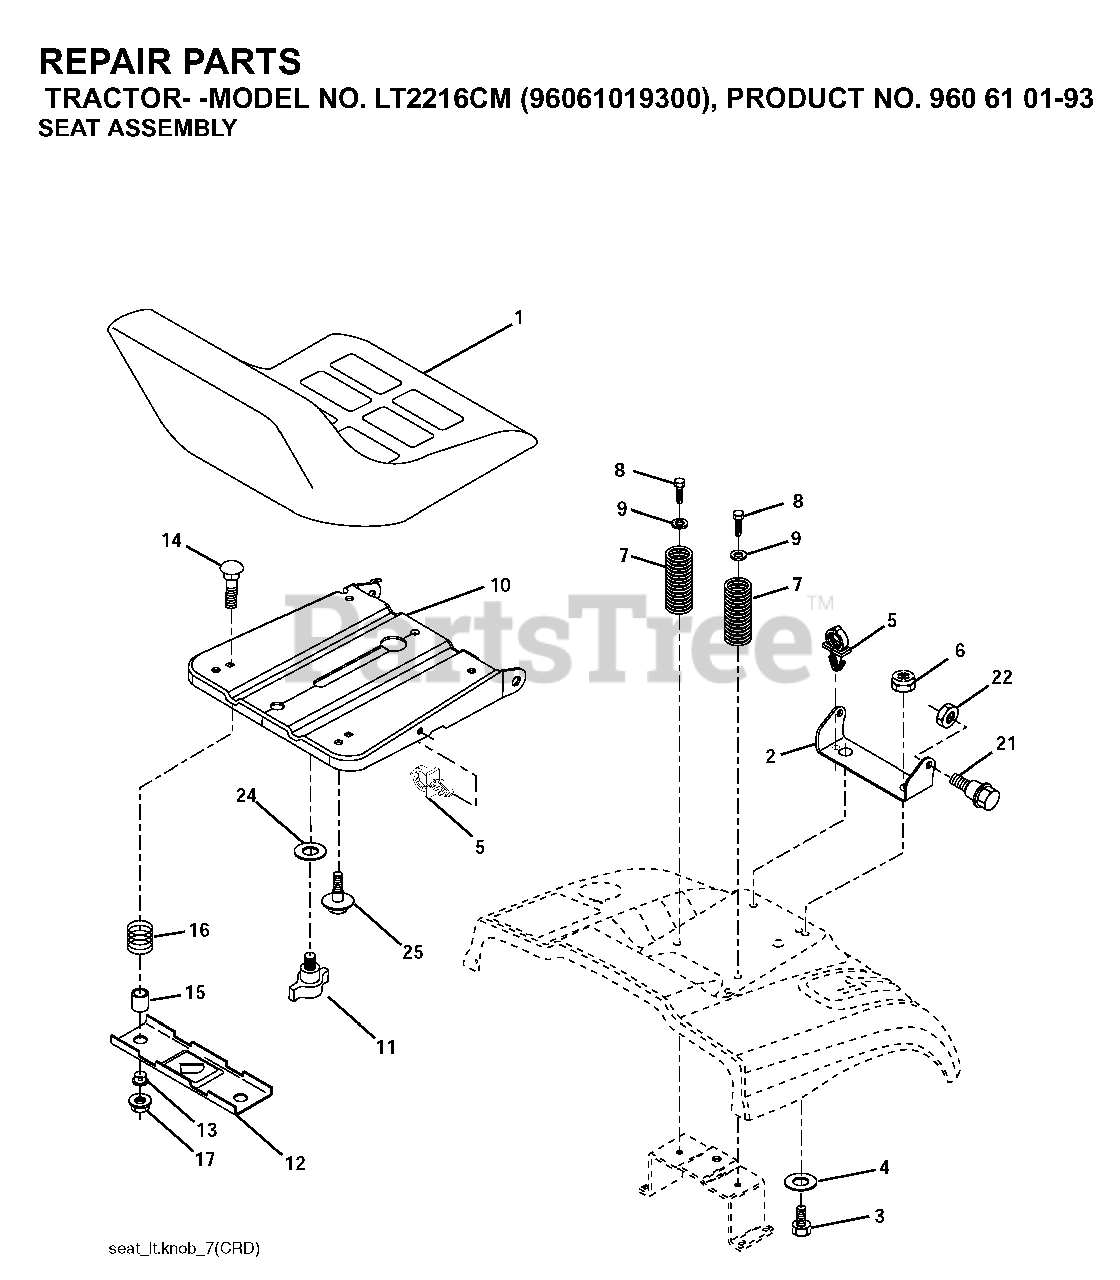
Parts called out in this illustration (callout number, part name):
2	SEAT PIVOT BRKT
4	WASHER PM
5	PUSH CLIP
6	NUT
7	SPRING COMPRESSION
8	SCREW 3/8-16X1
9	WASHER
10	PAN.ASM.SEAT.1SLOT
11	KNOB.SEAT.ADJ.WINGNUT
12	BRKT.MNTNG.SWITCH.SEAT
14	BOLT.ROUND.HEAD.SQUARE.NECK
15	SPACER SPLIT 28X.96
17	NUT T
21	BOLT.SHOULDER.5/16-18
22	NUT.71038.31-18.HEX.NYLOCK
25	BOLT,SHOULD
